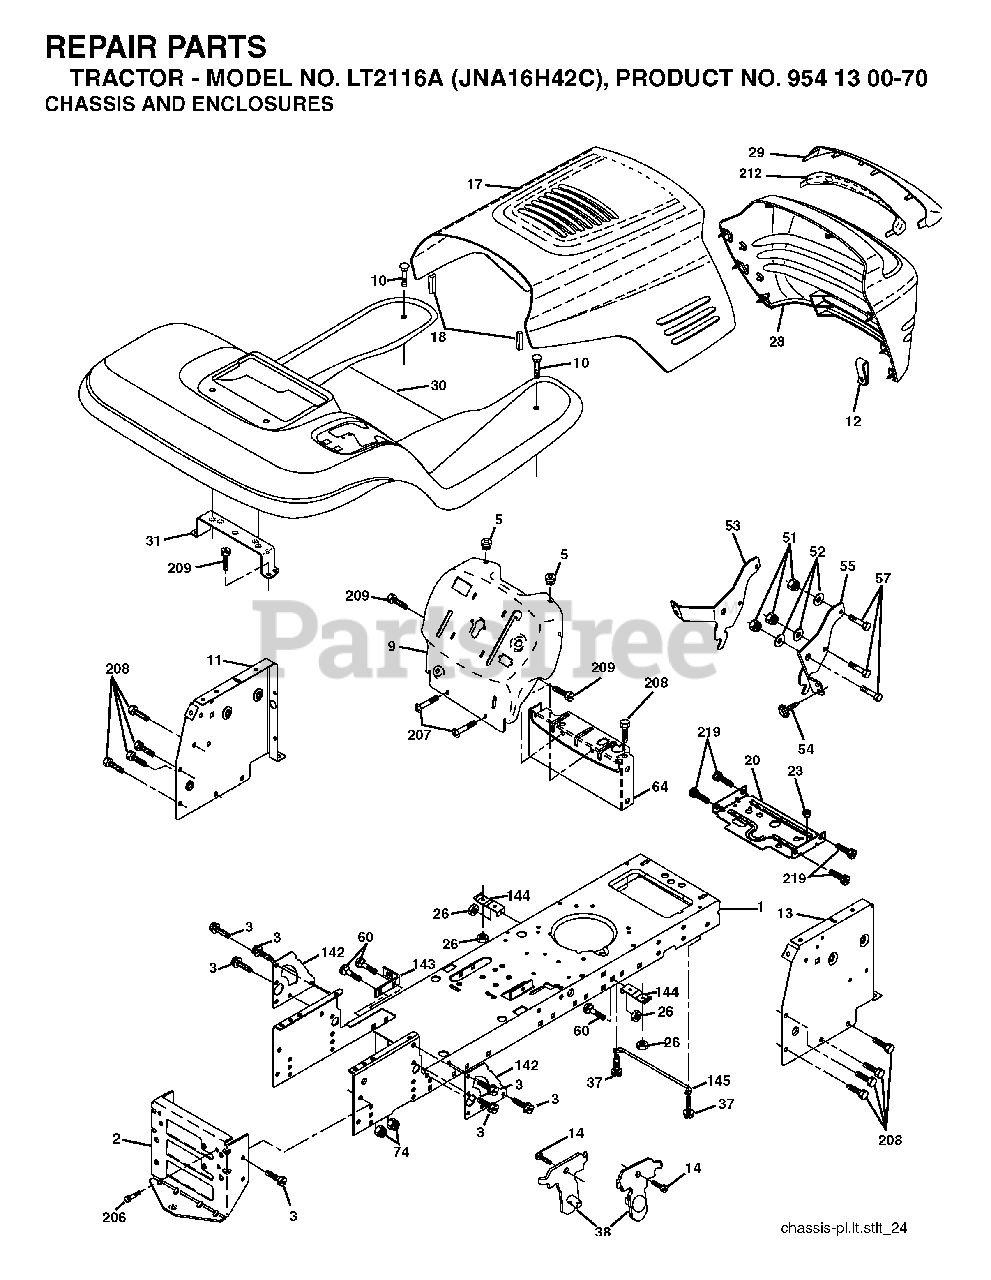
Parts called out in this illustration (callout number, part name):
1	CHASSIS STAMPING
2	DRAWBAR, 12GA
3	SCREW 3/8-16X3/4
5	BUMPER.RUBBER.HOOD
10	BOLT D
11	PANEL.DASH.LH.LTX
13	PANEL ASM, DASH RH
18	BUMPER.HOOD.LARGE.1.75"
20	PLATE MTG.BATTERY/FUEL TANK
23	GROMMET T
26	NUT
28	GRILL/LENS ASM.
38	BRACKET.ASM.PIVOT.MOWER.REAR
51	LOCKNUT
53	BRACKET.GRILLE.LH
57	BOLT
64	DASH LOWER
74	LOCKNUT
142	PLATE REINFORCEMENT
143	BRACKET, SWAY BAR
144	BRKT, FOOT REST
145	ROD PIVOT CHASSIS/HOOD
206	SHOULDER BOLT 5/16-18TT
207	SCREW, 5/16-18 X 1/2
208	SCREW 3/8-16X1/2
209	SCREW, 3/8-16X3/4
219	SCREW
